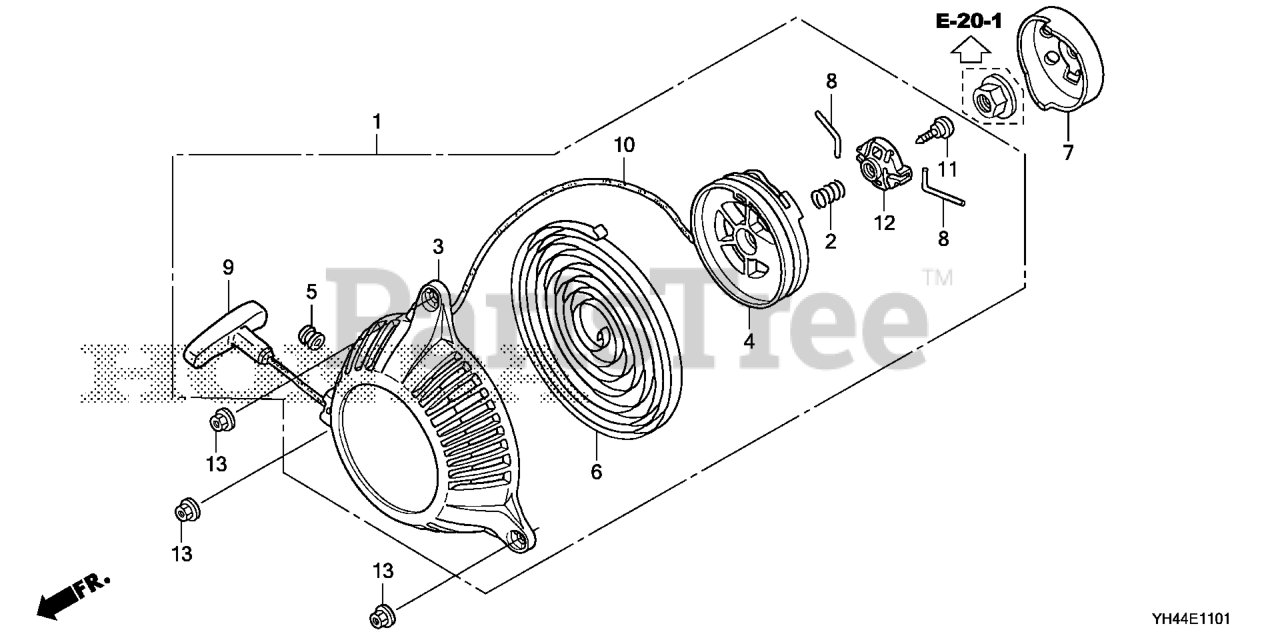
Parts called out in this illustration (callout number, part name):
1	STARTER ASSY., RECOIL
2	SPRING, FRICTION
3	CASE, RECOIL STARTER
4	REEL, RECOIL STARTER
5	GUIDE, ROPE
6	SPRING, RECOIL STARTER
7	PULLEY, RECOIL STARTER
9	KNOB, RECOIL STARTER
10	ROPE, RECOIL STARTER
11	SCREW, SETTING
13	NUT, FLANGE (5MM)
